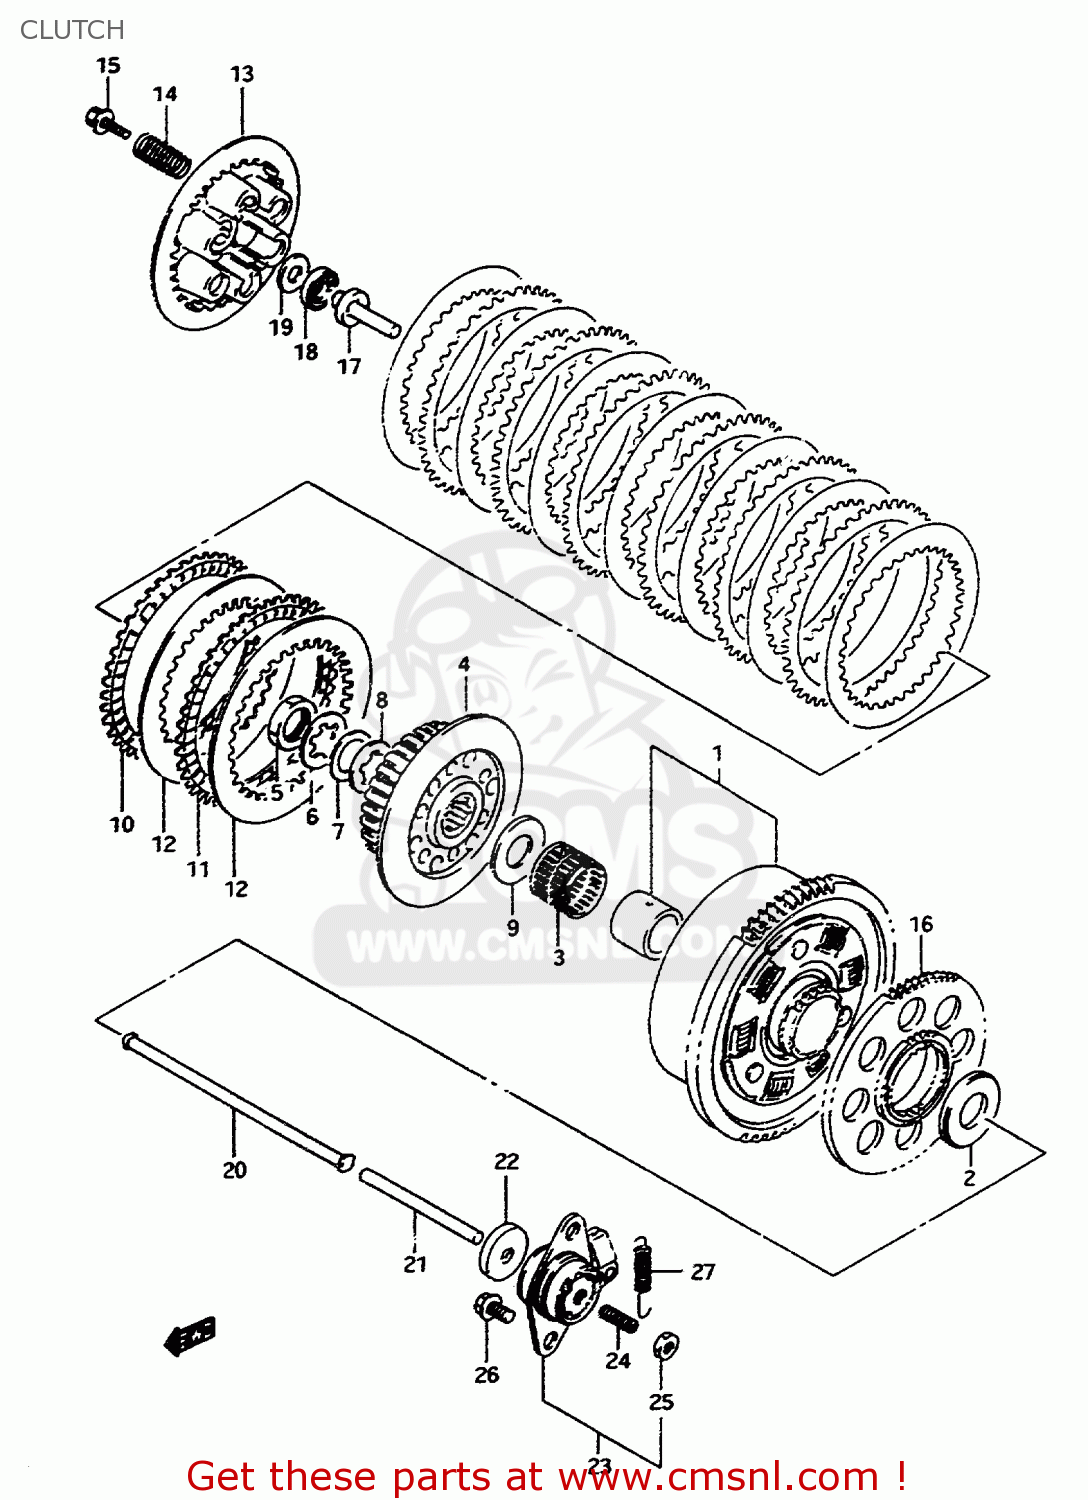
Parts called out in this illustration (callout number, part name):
1	GEAR ASSEMBLY,PRIMARY DRIVE
2	WASHER(25X54X2.5)
3	BEARING(35X40X35.8)
4	HUB,CLUTCH SLEEVE
5	NUT
6	WASHER,LOCK
7	WASHER
8	WASHER,LOCK
9	WASHER(25X50X2.5)
10	PLATE,CLUTCH DRIVE (NAS)
11	PLATE,CLUTCH DRIVE NO.2 (NAS)
12	PLATE,CLUTCH DRIVEN (NAS)
13	DISC,CLUTCH PRESSURE
14	SPRING
15	BOLT(6X25)
16	GEAR,GENERATOR DRIVE,N
17	PIECE,CLUTCH PUSH
18	BEARING(15X28X2)
19	WASHER(15.5X28X1)
20	ROD,CLUTCH PUSH,R
21	ROD,CLUTCH PUSH,L
22	SEAL,OIL(6X34X5.5)
23	SCREW ASSY,CLUTCH RELEASE
24	SCREW(6X25)
25	NUT
26	BOLT
27	SPRING
